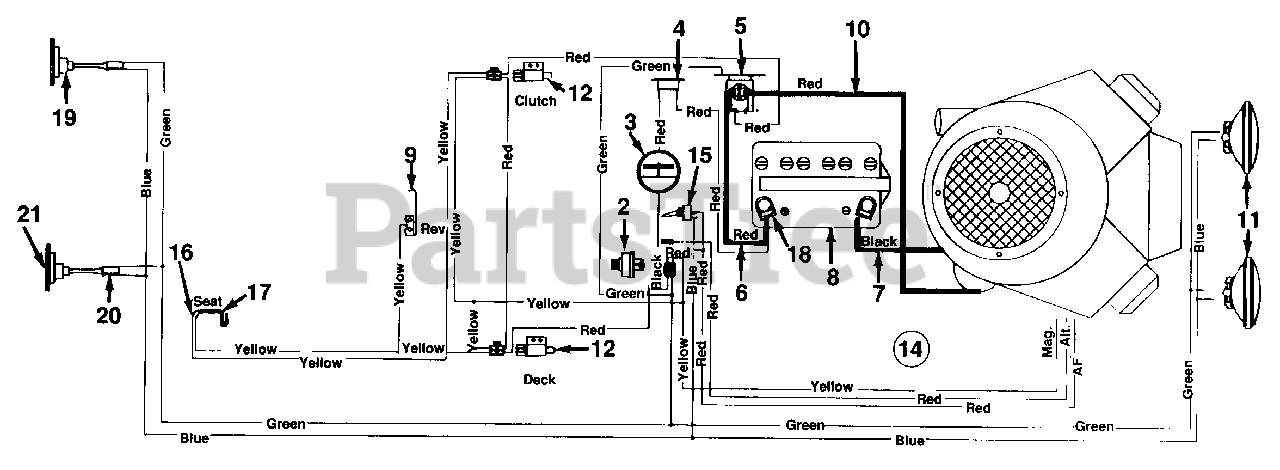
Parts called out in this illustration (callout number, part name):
2	Ignition Switch
3	Ammeter
4	Circuit Breaker 20 Amp
5	Solenoid
6	Electric Wire
7	Electric Wire
8	Battery
9	Spring Switch
10	Electric Wire
11	Headlights
12	Safety Switch
14	Wire Harness
15	Light Switch
16	Safety Switch
17	Safety Switch
18	Battery Boot
19	Tail light
20	Tail light Harness
21	Tail light Bulb
